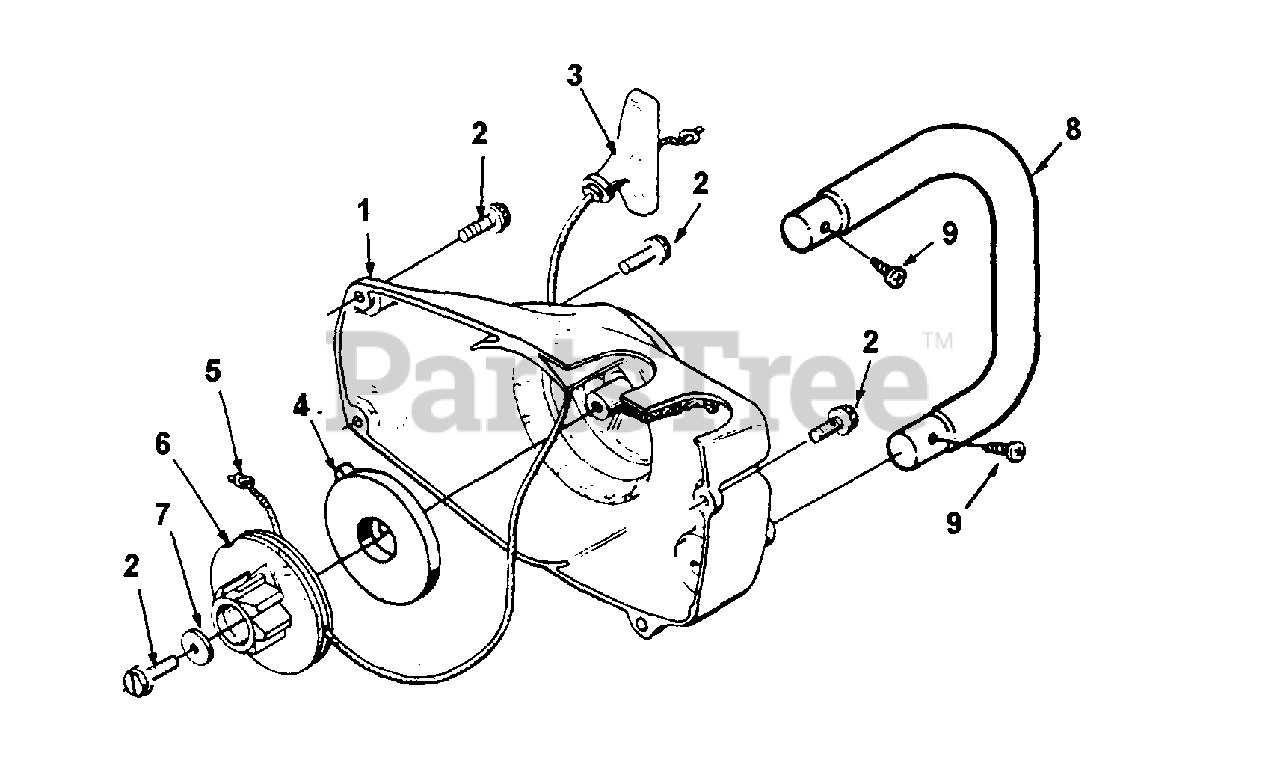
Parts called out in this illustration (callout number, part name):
1	RECOIL STARTER ASSY.
2	SCREW, SELF TAPPING (10-24 x 3/4")
3	GRIP, STARTER
4	SPRING, REWIND
5	ROPE, STARTER
6	PULLEY, STARTER
7	WASHER, RETINING
8	HANDLE ASSY.
9	SCREW, PAN HEAD (10-26 x 3/4")
